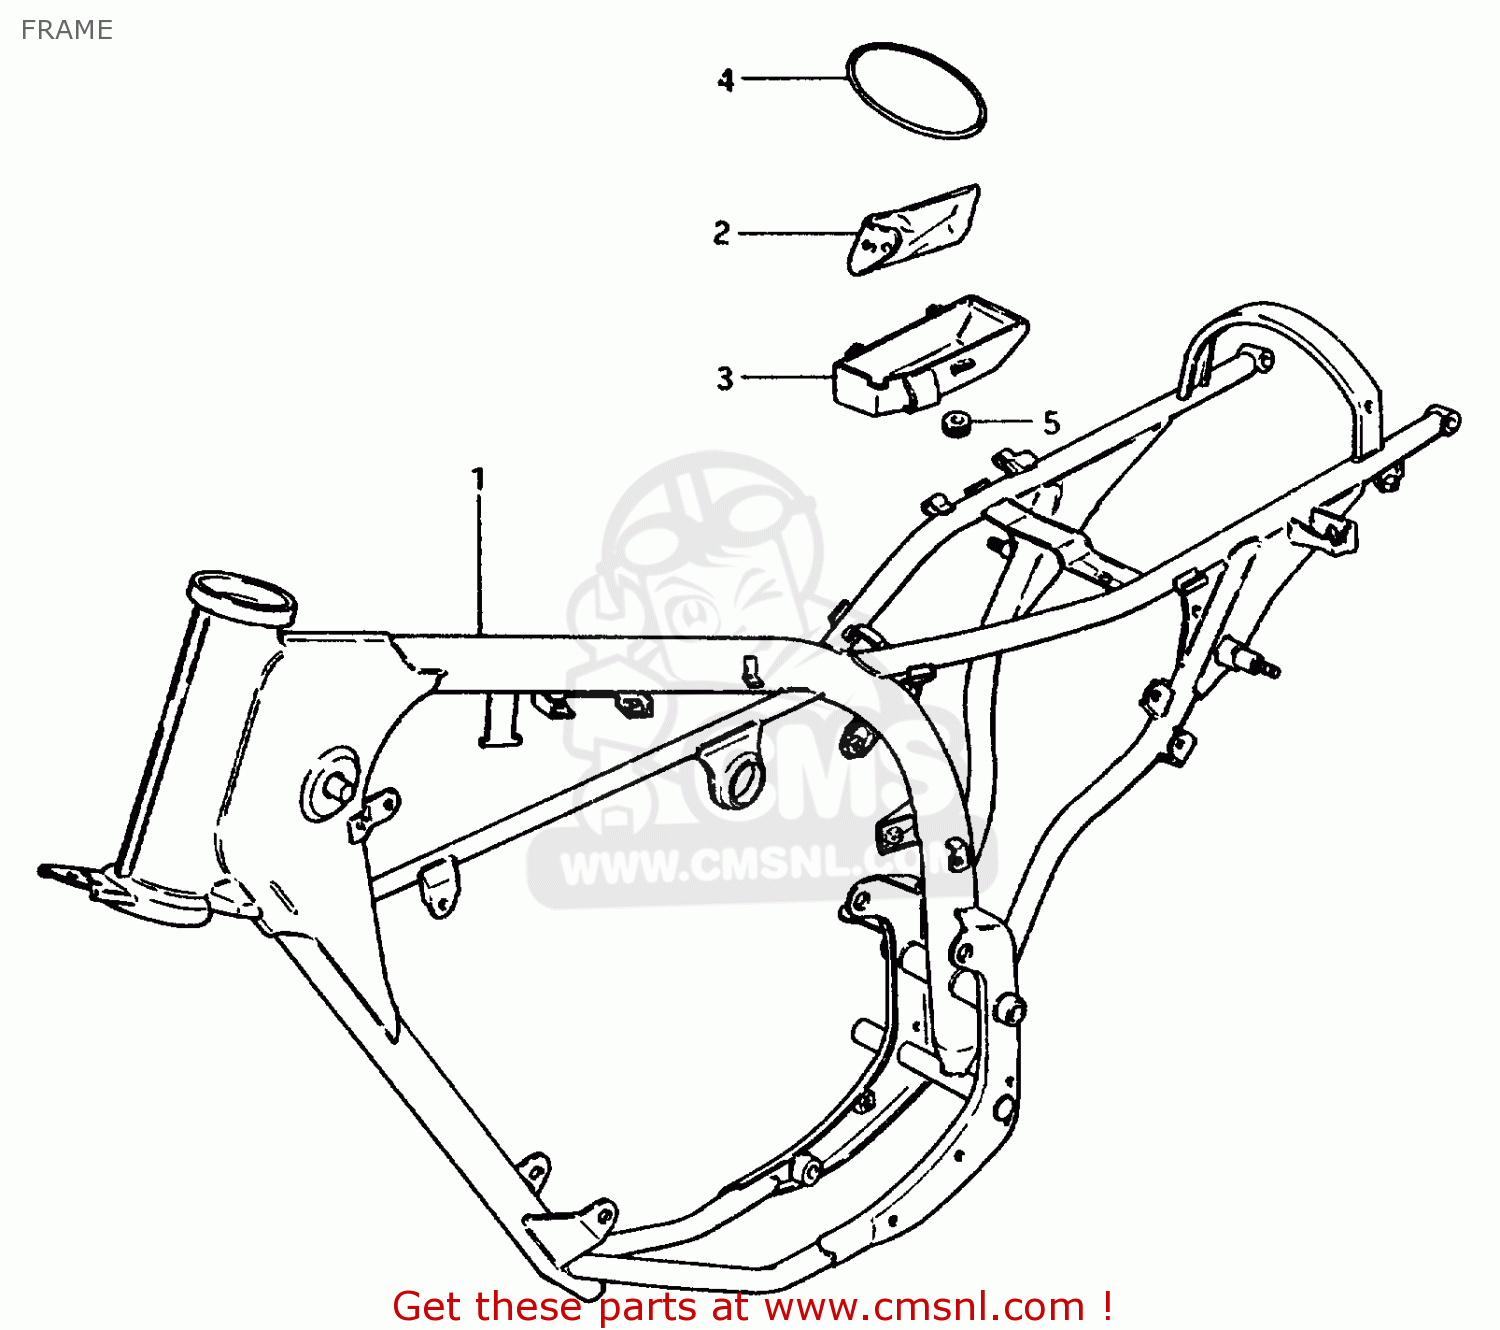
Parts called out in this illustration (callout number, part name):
1	FRAME (BLACK)
2	TOOL SET
3	HOLDER, TOOL
4	O RING(D:3.5,ID:76)
5	CUSHION
